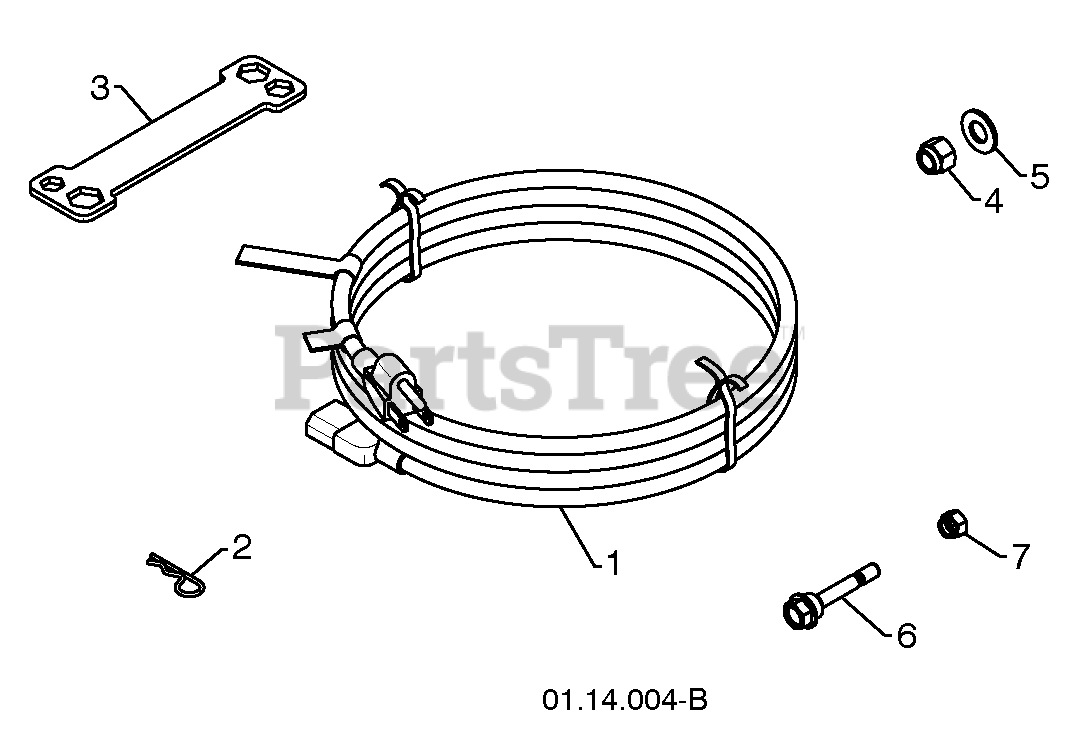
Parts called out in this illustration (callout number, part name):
1	POWER CORD
2	RETAINER PIN
3	WRENCH
4	LOCKNUT 3/8-16
5	WASHER 3/8
6	SHEAR BOLT 1/4-20 X 1-3/4
7	LOCKNUT 1/4-20
